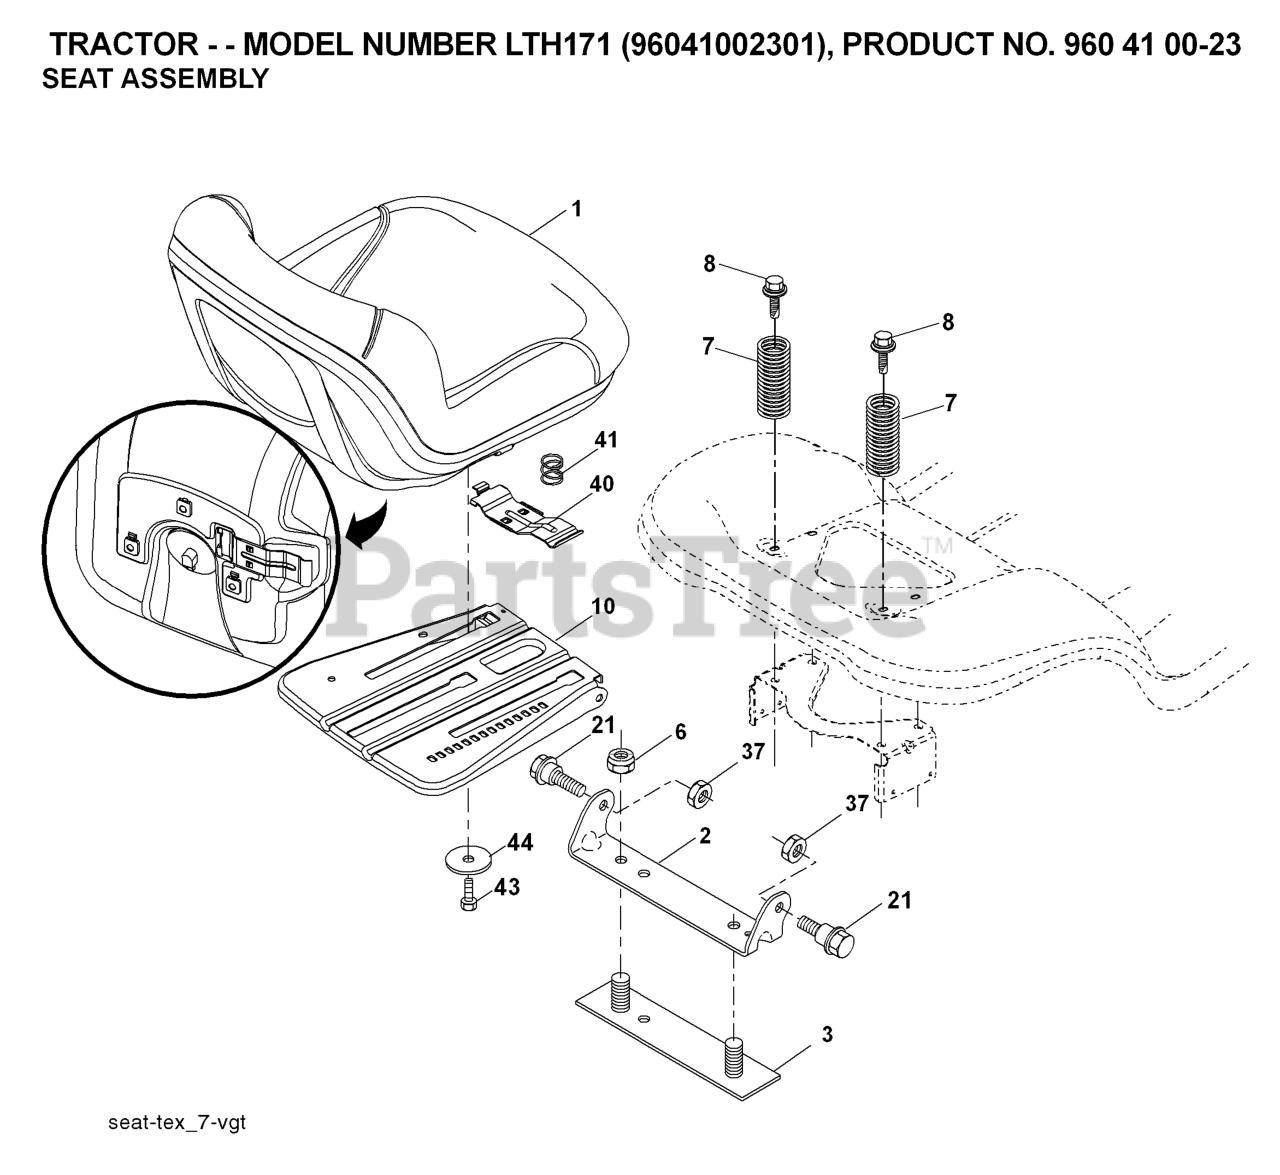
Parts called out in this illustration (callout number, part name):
1	BELT, 21 MOWER
2	RHSNB, 1/4-20 X 1, GR5
3	DRIVEN PULLEY
4	CABLE BRACKET
6	TRANSMISSION SPACER
7	HCS, 1/4-14 X 1 1/2, SELF TAP
8	PIVOT BUSHING
9	SHAFT COVER
10	SPIRAL PIN, 3/16 X 1 1/8
11	TRANSMISSION W/GREASE SLOT T13
12	NUT.1/4-20.HEX.NYLOC.ZD
13	WASHER 1/4 FLAT
14	SCREW, 1/4-14 X 3/4, SELF TAP
15	SPRING, TRANSMISSION
16	KEY SPRING
17	WOODRUFF KEY, SPECIAL
